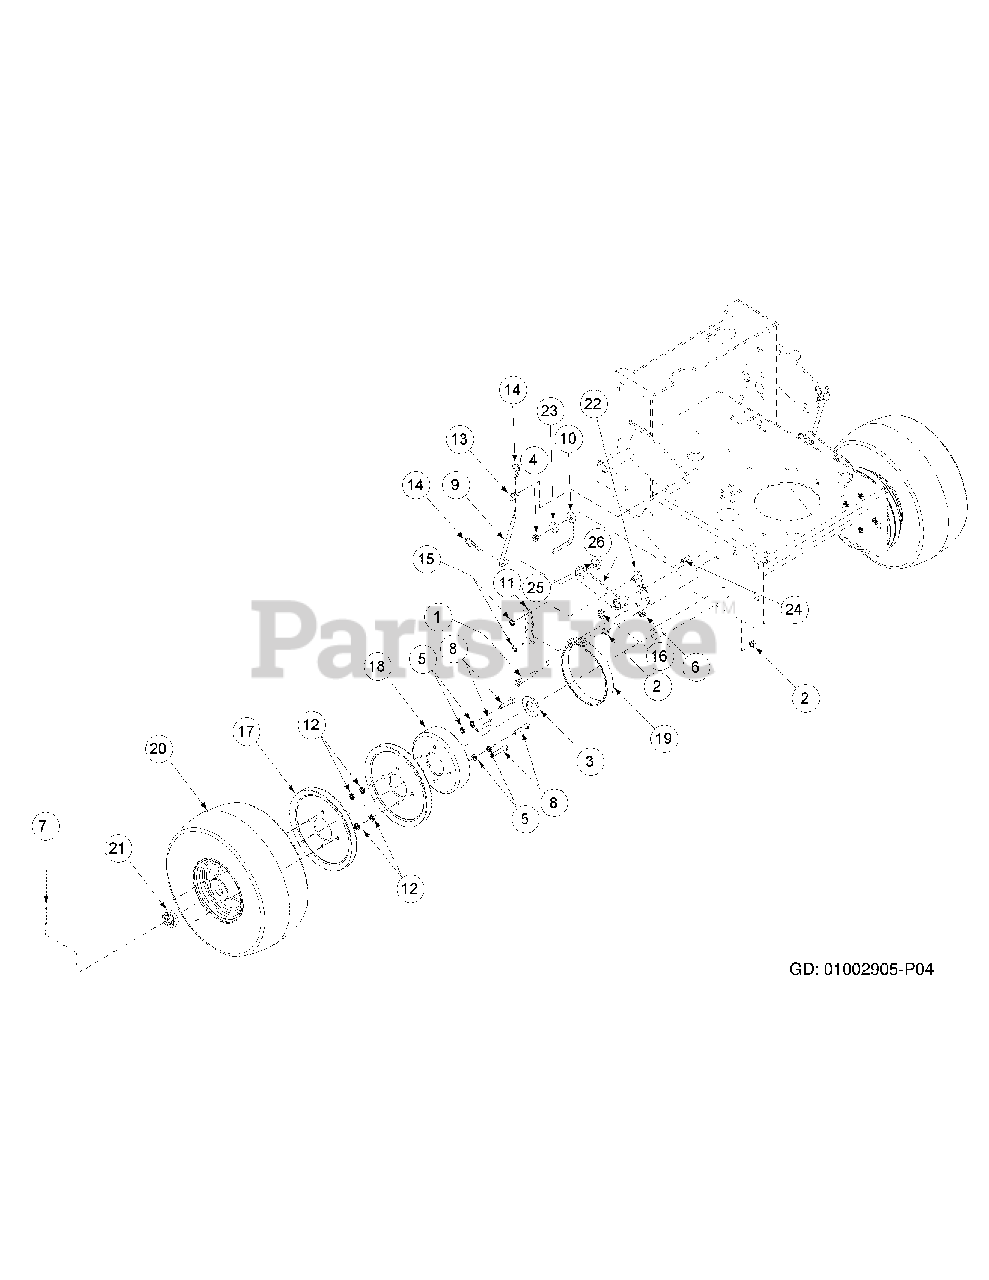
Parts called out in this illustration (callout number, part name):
1	Hex Cap Screw, 3/8-16 x 2.00
2	Hex Nut, 3/8-16
3	Flat Washer, 2.000 x 1.005
4	Nut, Nylock, 5/16-18
5	Lock Washer, 5/16 Zinc
6	Grease Fitting, 1/4-28, 90 degree
7	Cotter Pin, 5/32 x 1-1/2 Zinc
8	Hex Cap Screw, 5/16-18 x 1-1/2
9	Brake Rod
10	Drive Belt Guide
11	Brake, Bracket Link
12	Drive Wheel Pulley Spacer
13	Swivel Joint
14	Hair Pin, 3/8-1/2
15	Retainer, Push ON, 3/8
16	E-Ring, 5/8
17	Drive Pulley, V
18	Drum Brake
19	Band Brake
20	Wheel Assembly, 13 x 6.50-6
21	Hex Jam Nut, 1-14
22	Brake Link
23	Idler Washer
24	Carriage Bolt, 5/16-18 x 1
25	Flat Washer, 5/16
26	Brake Lever Weldment
